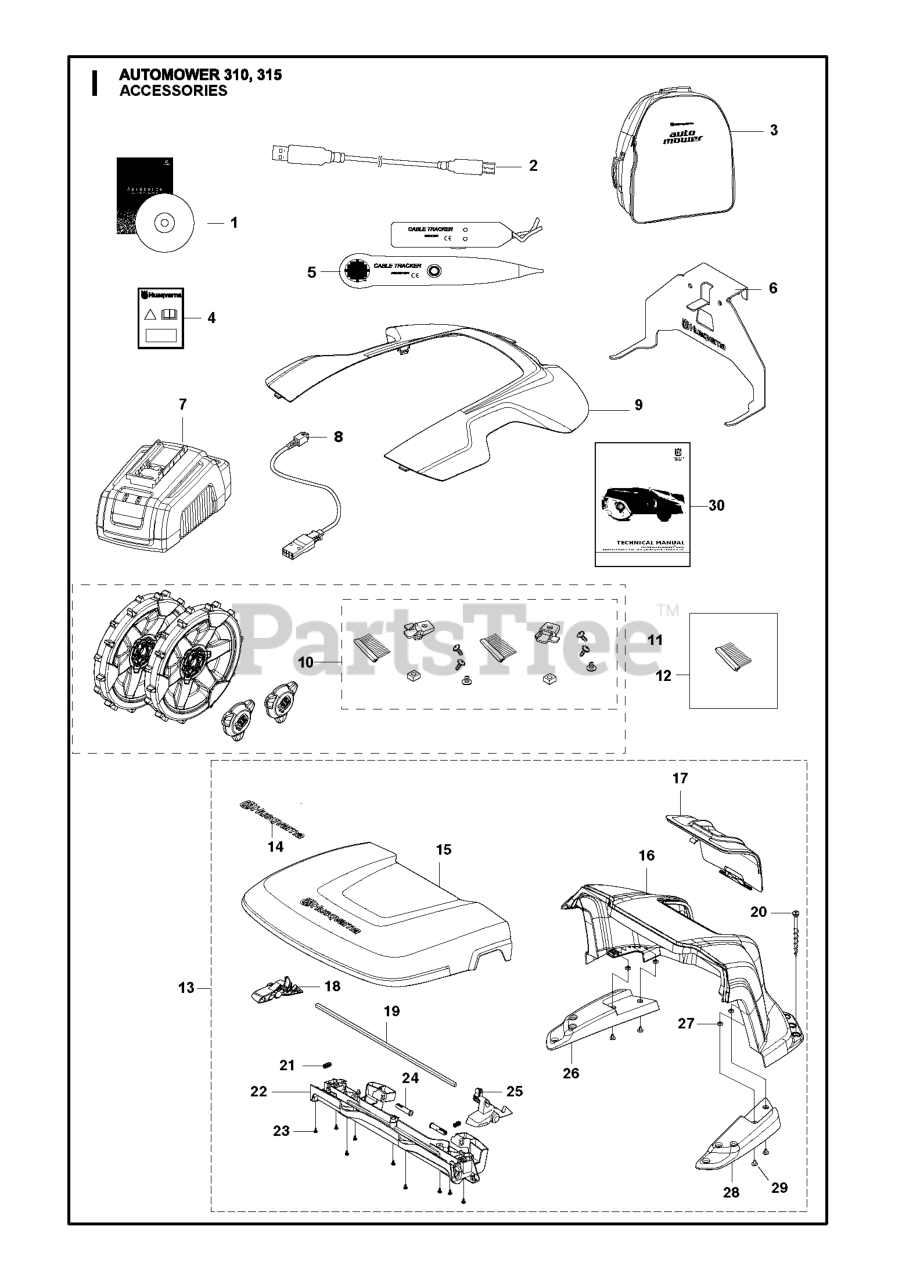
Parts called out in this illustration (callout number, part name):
1	DVD AUTOCHECK EXP SERVICE
2	CABLE WHITE ALT GREY
4	LABEL WARRANTY SEAL DEALER
5	TEST EQUIPMENT
6	315 WALL HANGER
7	CHARGER BATTERY TEST
8	CABLE ASSY QUICK CHARGER
9	ORANGE COVER
9	WHITE COVER
9	GREY COVER
10	WHEEL BRUSH KIT 315
11	WHEEL KIT AM310/315. HEAVY REA
12	BRUSH WITH CARTON
13	HOUSE KIT FOR 315
14	DECAL.HUSQVARNA.210MM
15	COVER LID 315
16	COVER BASE P15
18	HANDLE RELEASE LEFT
20	SCREW KIT CS
21	SPRING SPRING CAP
23	SCREW 14MM
25	HANDLE RELEASE RIGHT
26	SUPPORT BASE LEFT
28	SUPPORT BASE RIGHT
29	SCREW IHPANM M6X25 4.6 ZP-BC
